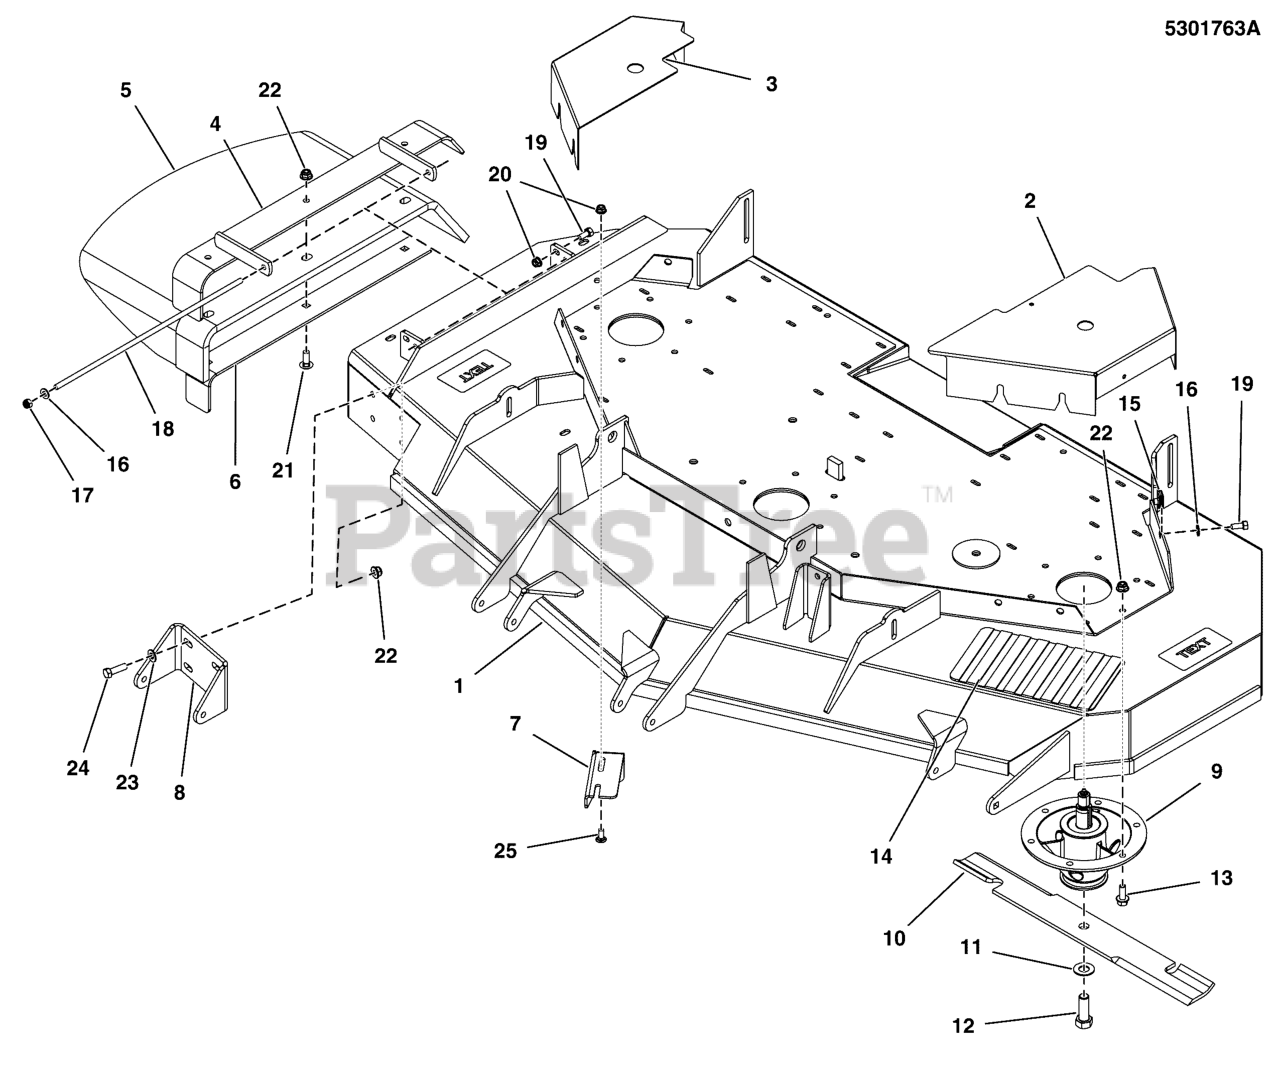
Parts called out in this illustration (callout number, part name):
1	DECK SHELL W/DECALS, 61, 200XT (5416054D)
1	DECK SHELL W/DECALS,61,S200XT(5417036D)
2	GUARD, 61 - LH - RED
3	GUARD, RH - 61 - S200XI - RED
5	CHUTE, RUBBER DISCHARGE (5104442)
6	SUPPORT, DISCHARGE CHUTE - BLK
7	PLATE, DEFLECTOR - BLK
8	PLATE, BRACKET, ANTI SCALP, RH - 61 -RED
9	SPINDLE ASSM, CAST IRON 8.0 - 6-BOLT
10	BLADE SET, 61 DECK (3)
11	WASHER, BLADE BOLT, 9/16" F436, CZ
12	BOLT, 5/8-11 X 1-3/4 GD8
13	BOLT, 3/8-16 X 1, FLANGE, GD 5, CZ
14	SAFETY WALK, 9.75 X 6.00
15	BODY CLIP, 5/16-18-7GA MATERIAL
16	WASHER, 5/16" SAE
17	NUT, 5/16-24 HEX NYLON LOCK
18	ROD, MOUNT, CHUTE, 61, CZ
19	BOLT, 5/16-18 X 3/4 GD5
20	NUT, 5/16-18 HEX NYLOCK FLANGE NUT
21	BOLT, 3/8-16 X 1-1/2, CARRIAGE, GD5, CZ
22	NUT, 3/8 - 16 HEX NYLOCK FLANGE
23	WASHER, 3/8 SAE
24	BOLT, 3/8-16 X 1-1/4" GD5 CZ
25	BOLT, 5/16-18 X 3/4, CARRIAGE, GD5, CZ
